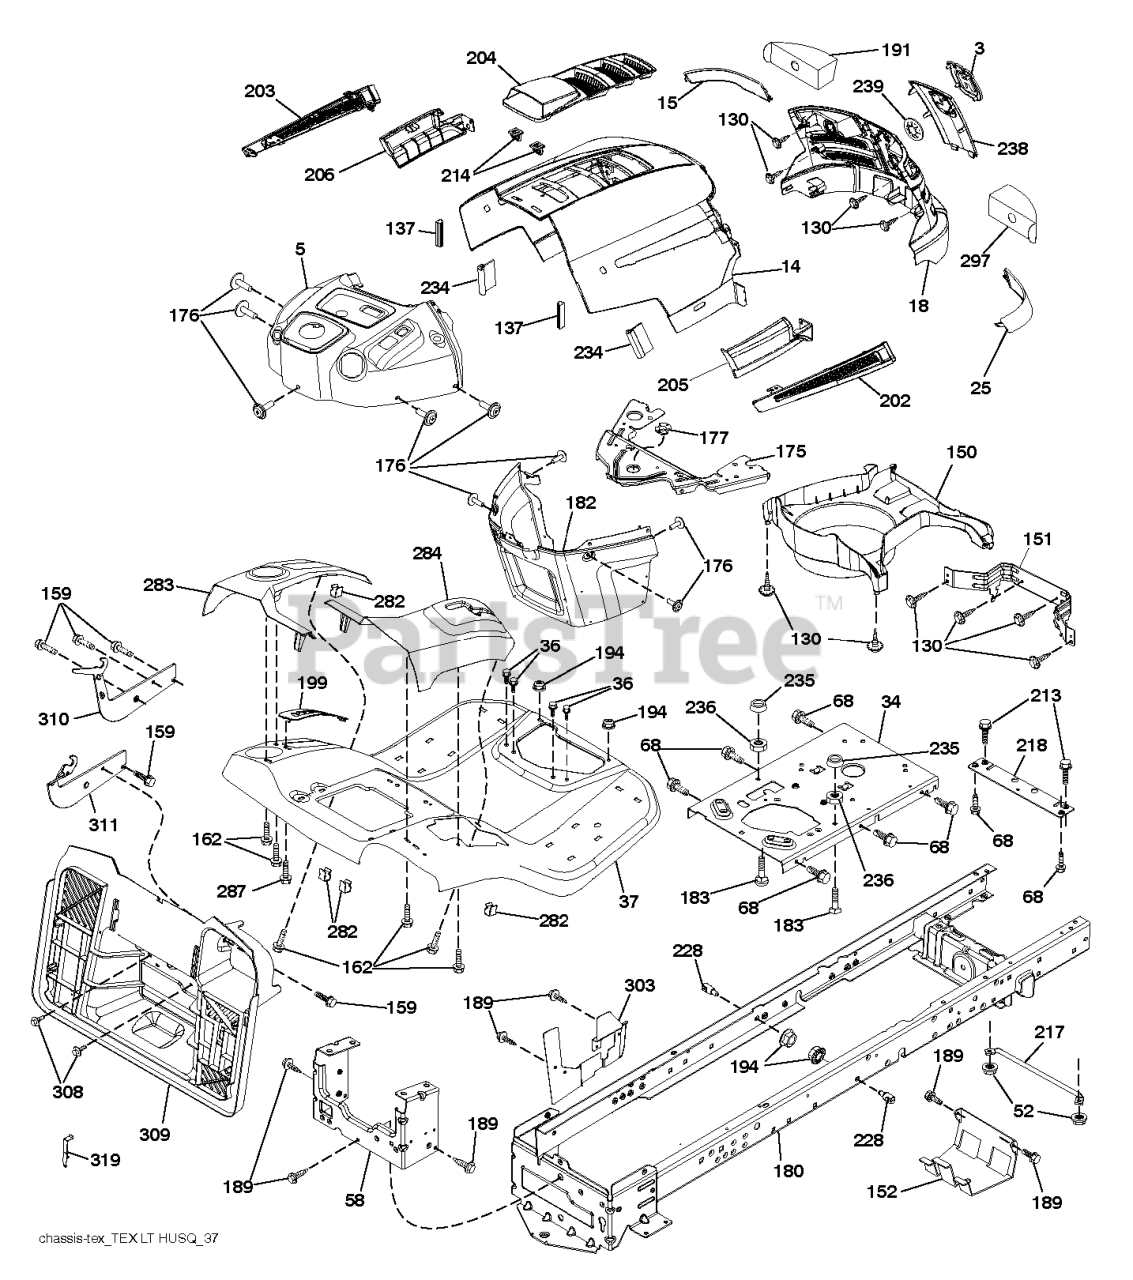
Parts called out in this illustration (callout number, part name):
3	RP LOGO
5	DASH
14	HOOD.HUSQVARNA.LT.MS422
15	LENS.HUSQVARNA LT.LH
18	RP GRILLE/LENS ASM.
25	LENS.HUSQVARNA LT.RH
34	PLATE.ENGINE.WELDED.CHASSIS
36	SCREW 5/16"
37	FENDER.PNT.SRD.30R
52	LOCKNUT
58	DRAWBAR UPPER 2PC SMALL FENDER
68	Screw 5/16-18 x 1/2 Hex, Self Tapping 5/16-18 x 1/2
130	SCREW.#10 X 0.750.BOS
137	BUMPER DASH
151	BRACKET PIVOT
152	SHIELD.BROWNING.W/TEX
159	SCREW, 3/8-16X3/4
162	SCREW.HI-LO.CONSOLE
175	CROSSMEMBER
176	SCREW.#10-24X5/8.RN.QU
177	BUSHING STEERING
180	CHASSIS.WLDMNT.14GA.2PC.18".TI
182	DASH.LOWER.PREDATOR LT
183	BOLT.5/16-18X1-1/4 FULL.THREAD
189	SCREW
191	INSERT REFLECTIVE
194	NUT LOCK HEX FLANGE 5/16-18
199	PLATE DECK LIFT
202	VENT SIDE HOOD LH
203	VENT SIDE HOOD RH
204	VENT TOP HOOD
205	SKIRT SIDE RH
206	SKIRT SIDE LH
213	BOLT
214	CLIP.RETAINER.TINNER.
217	ROD.PIVOT.HOOD
218	X-PIECE.HOOD.STOP.NON/
228	STUD.FASTNER.W/ANTI-ROTATE
234	BUMPER.HOOD.TEX.HUSQVARNA
235	SPACER FENDER
236	NUT.CENTERLOCK.5/16-
238	TRIM
282	CLIP.RETAINER.CONSOLE.LT.HUSQ
283	CONSOLE.DCKLFT.SRD.BGR
284	CONSOLE.SHFT.SRD.RH.PE
287	SCREW 1/4X20
297	INSERT.REFLECTIVE.RH.
303	SHIELD CHASSIS LEFT
308	BOLT.5/16-18UNCX3/4 W/SEMS.BLK
309	BACKPLATE.BAGGER.V2.SRD
310	Bracket Hangar Bag LH
311	Bracket Hangar Bag RH
319	BRACKET.ACTUATOR.BAGGER.SRD
